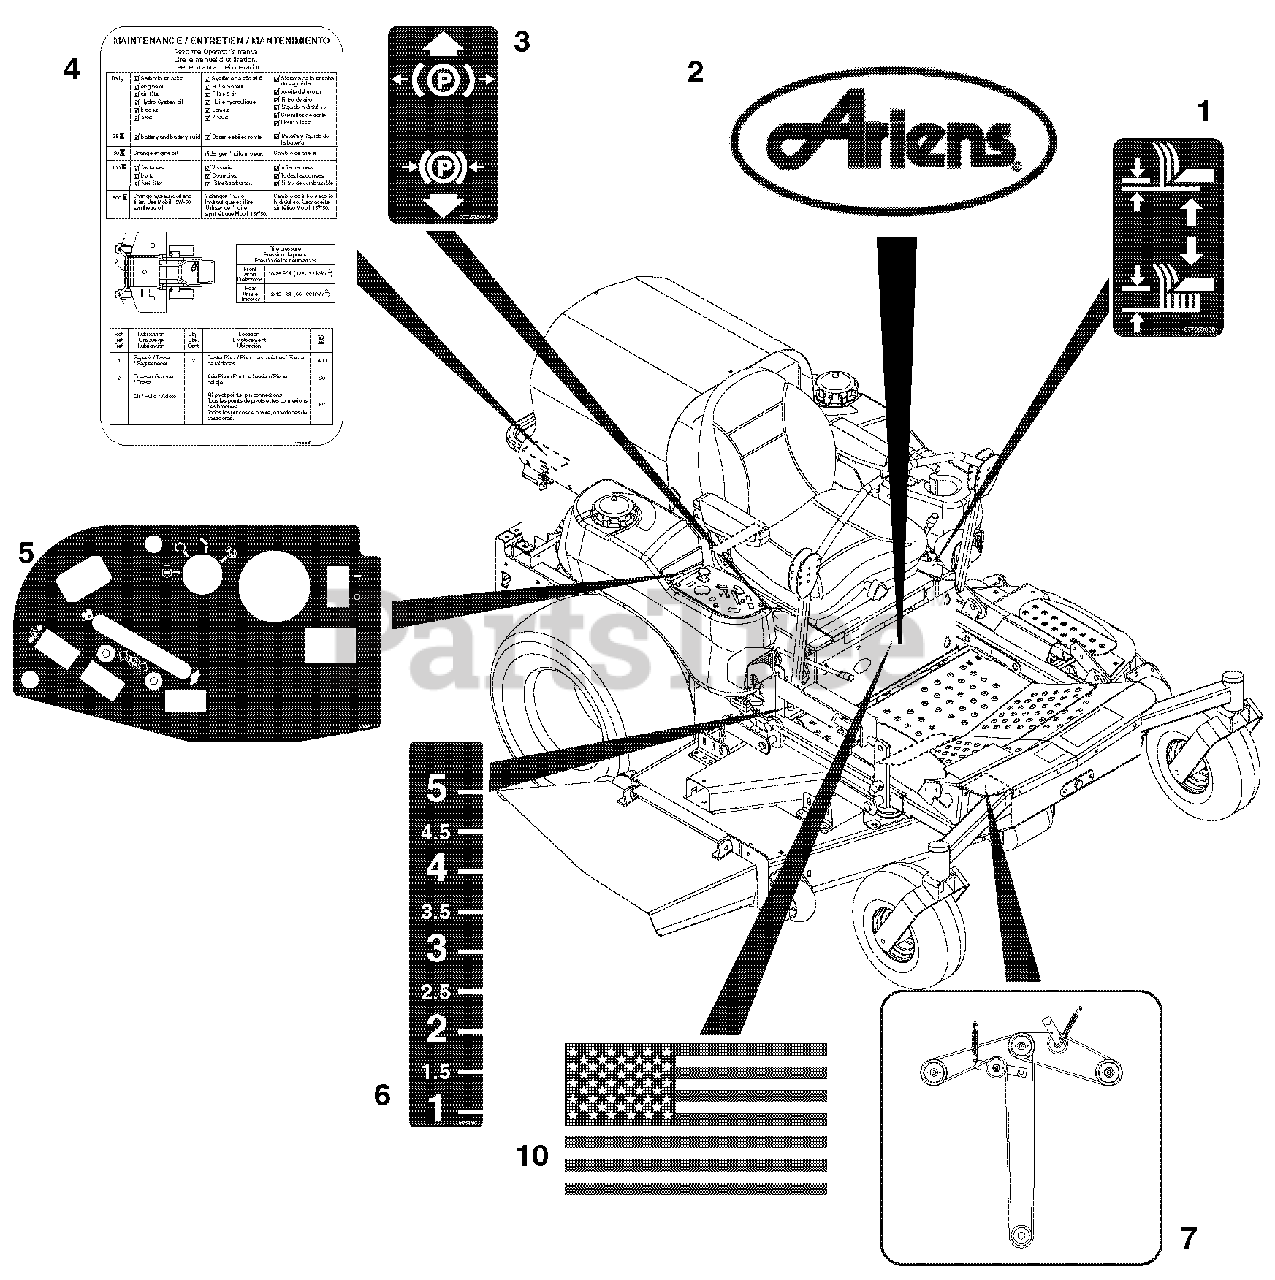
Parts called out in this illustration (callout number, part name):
1	Decal, Lift Lever
2	Decal, Ariens
3	Decal, Parking Brake Lever
4	Decal, Service Instructions
5	Decal, Control Panel
6	Decal, Height of Cut
7	Decal, Belt Diagram
8	Decal, PM-260Z
9	Decal, 60
10	Decal, American Flag
